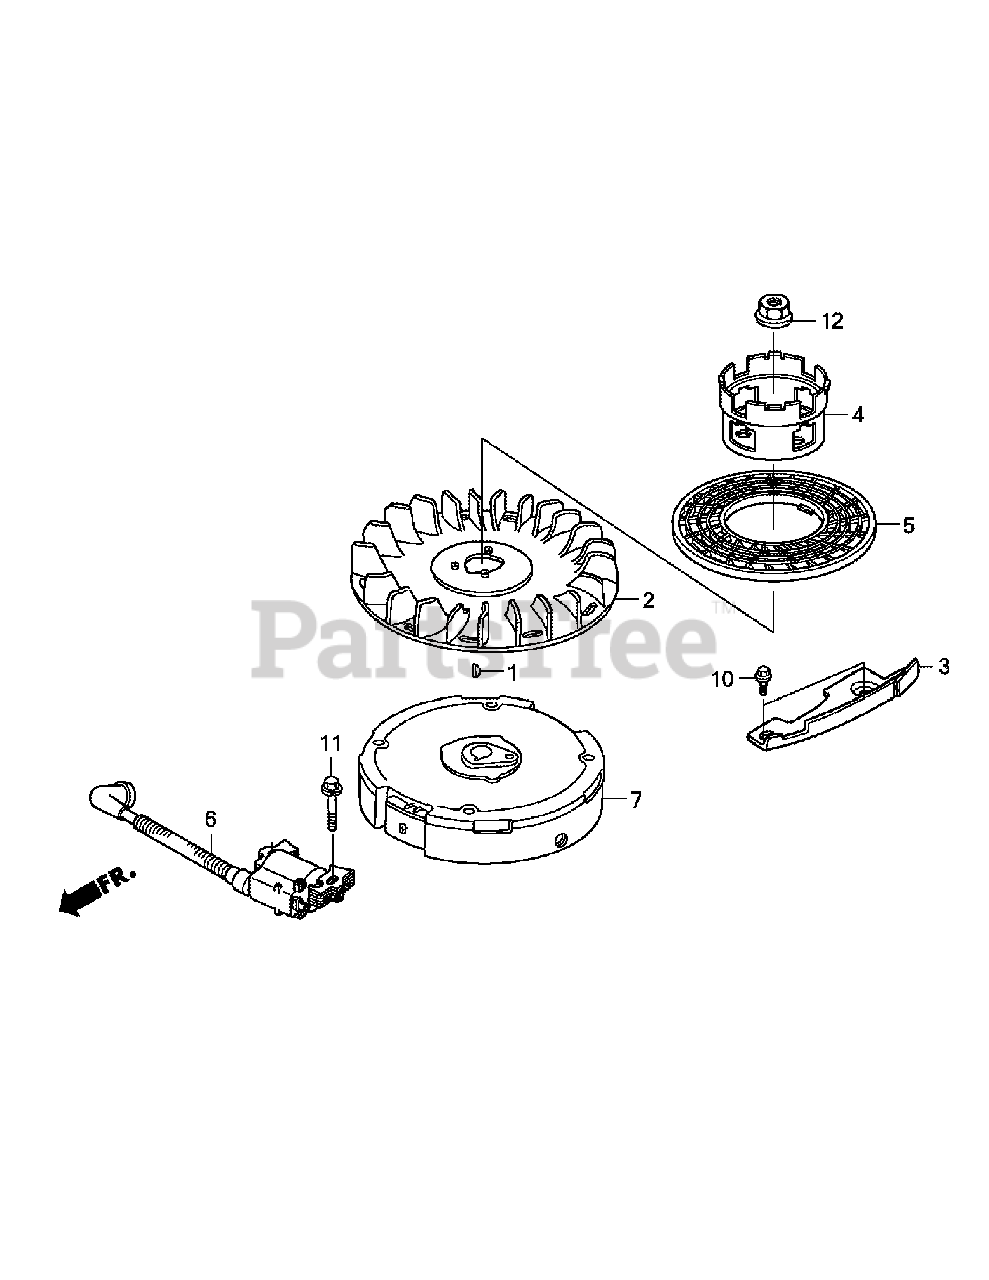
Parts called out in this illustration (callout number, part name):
1	Woodruff Key
2	Cooling Fan
3	Side Plate
4	Starter Pulley
6	Ignition Coil Assembly
7	Flywheel
10	Flange Bolt, 6 x 12
11	Flange Bolt, 6 x 23
